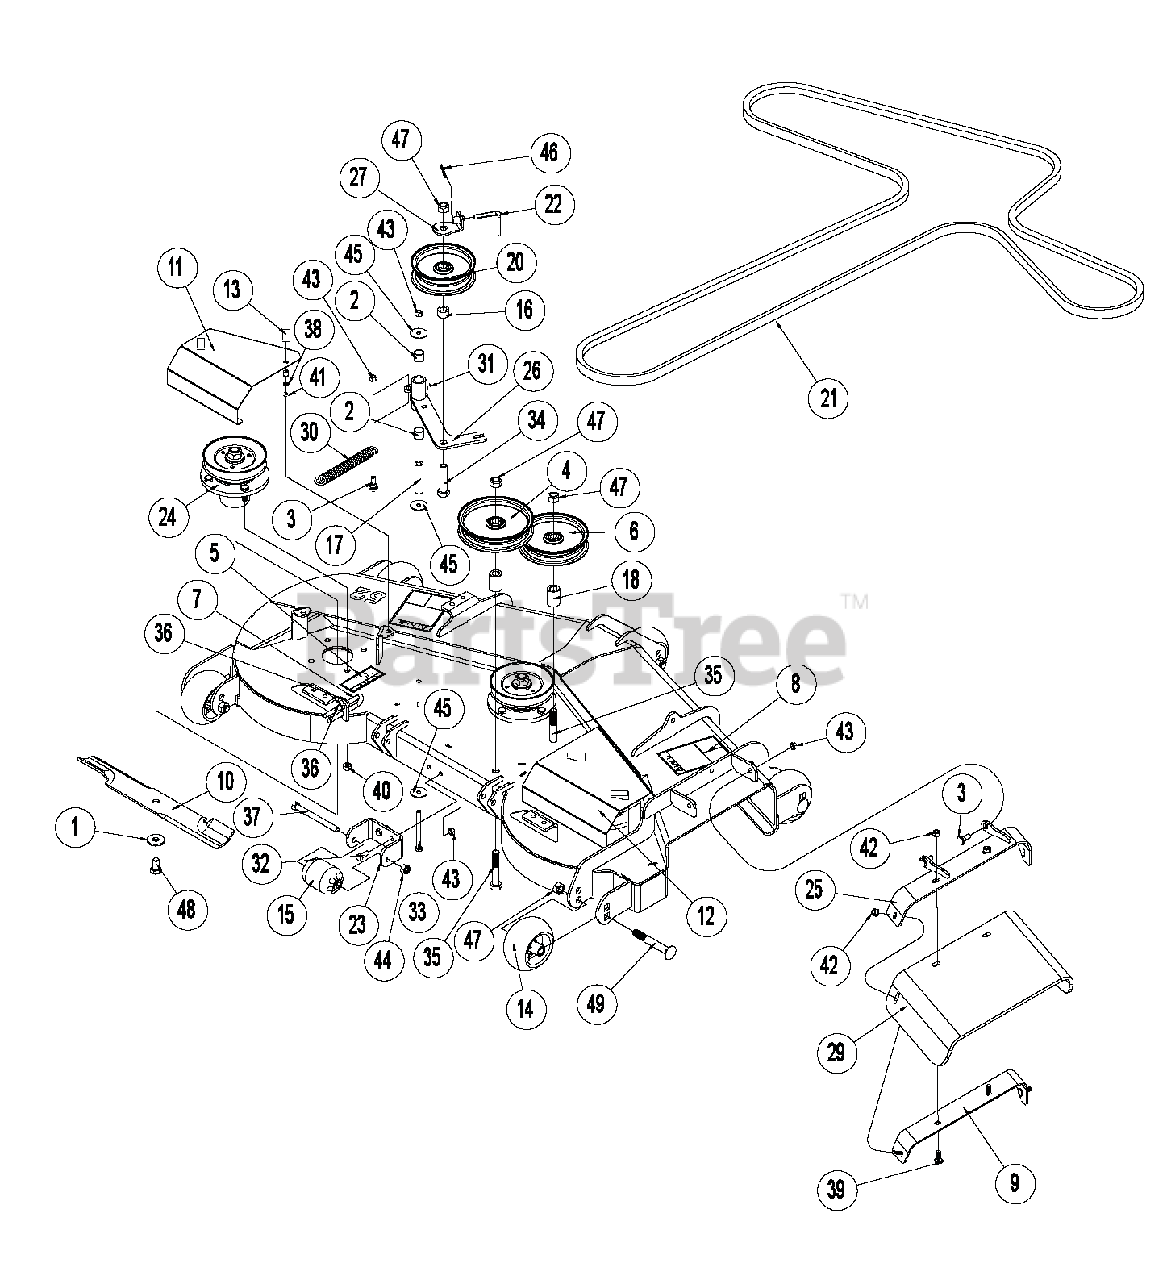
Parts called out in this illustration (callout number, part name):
1	WASHER, M14XM40XM4.5 FLAT Y
2	BRG, SLV .753X.878X.750
3	BOLT, 1/2X1.06X3/8-16 SLD 5 Y
4	PULLEY, FLAT 6.00X.635 W/BRG
5	DECAL, WARNING - SHIELD
6	PULLEY, FLAT 5.50X.635 W/BRG
7	U-BOLT, RD .63X4.50X3/8-16SP Y
8	DECAL, DANGER - DECK
9	PLATE, DISCHG SHIELD SUPPORT
10	BLADE, 18.000 X 1.00 LIFT
10	BLADE, 16.500 X 1.00 LIFT
11	SHIELD, LH ZTM BELT
12	SHIELD, RH ZTM BELT
13	LATCH, 12-24 SOUTHCO
14	WHEEL, GAUGE 5.00 X 3.31
15	WHEEL, GAUGE 2.56 X 3.94 SYM
16	BUSHING, .688 X 1.13 X .625
17	TUBE, RD .750 X .156 X 3.05
18	BUSHING, .688IDX 1.13 X 1.68L
19	DECAL, DECK 52"
19	DECAL, DECK 48"
20	PULLEY, FLAT 5.00X.635 W/BRG
21	BELT, HB 148.0 OC AMD OHR
21	BELT, HB 140.9 EL AMD
22	BELT KEEPER, 90? W/HOLE
23	BRACKET, ANTI-SCALP
24	ASSY,42"SNOW HEAD
24	ASSY, SPINDLE BALL BRG
25	WLDT, DISCHARGE SHIELD BRACKET
26	WLDT, DECK BELT TENSIONER
27	WLDT, BELT KEEPER Y
28	ASSY, 52 HORN DECK W/DECAL S/O
28	ASSY, 48 HORN DECK W/DECAL S/O
29	SHIELD, RUBBER DISCHARGE
30	SPRING, EXT .910X.177X6.15 Y
31	FTG, 1/4-28 TPR 45 GREASE ZERK
32	BOLT, 3/8-16X1.00 HEX 5 Y
33	BOLT, 3/8-16X4.00 HEX 5 Y
34	BOLT, 5/8-11X2.75 HEX 5 Y
35	BOLT, 5/8-11X3.50 HEX 5 Y
36	NUT, 3/8-16 STD HEX GR5 Y
37	BOLT, M12X1.75X130 HEX 8.8 Y
38	WASHER, M6 REG FLAT Y
39	BOLT, 3/8-16X1.00 CRG 5 Y
40	NUT, 7/16-20 HEX GR5 Y
41	LOCKNUT, 12-24 NYLOC Y
42	LOCKNUT, 3/8-16 WHIZ Y
43	LOCKNUT, 3/8-16 CROWN Y
44	LOCKNUT, M12X1.75 NYLOC Y
45	WASHER, .375X1.50X.063 FLAT Y
46	RING, RUE .625 X .072 X 1.690
47	LOCKNUT, 5/8-11 CROWN Y
48	BOLT, 9/16-12X1.00 HEX 8 Y
49	BOLT, 5/8-11X4.50 CRG Y
